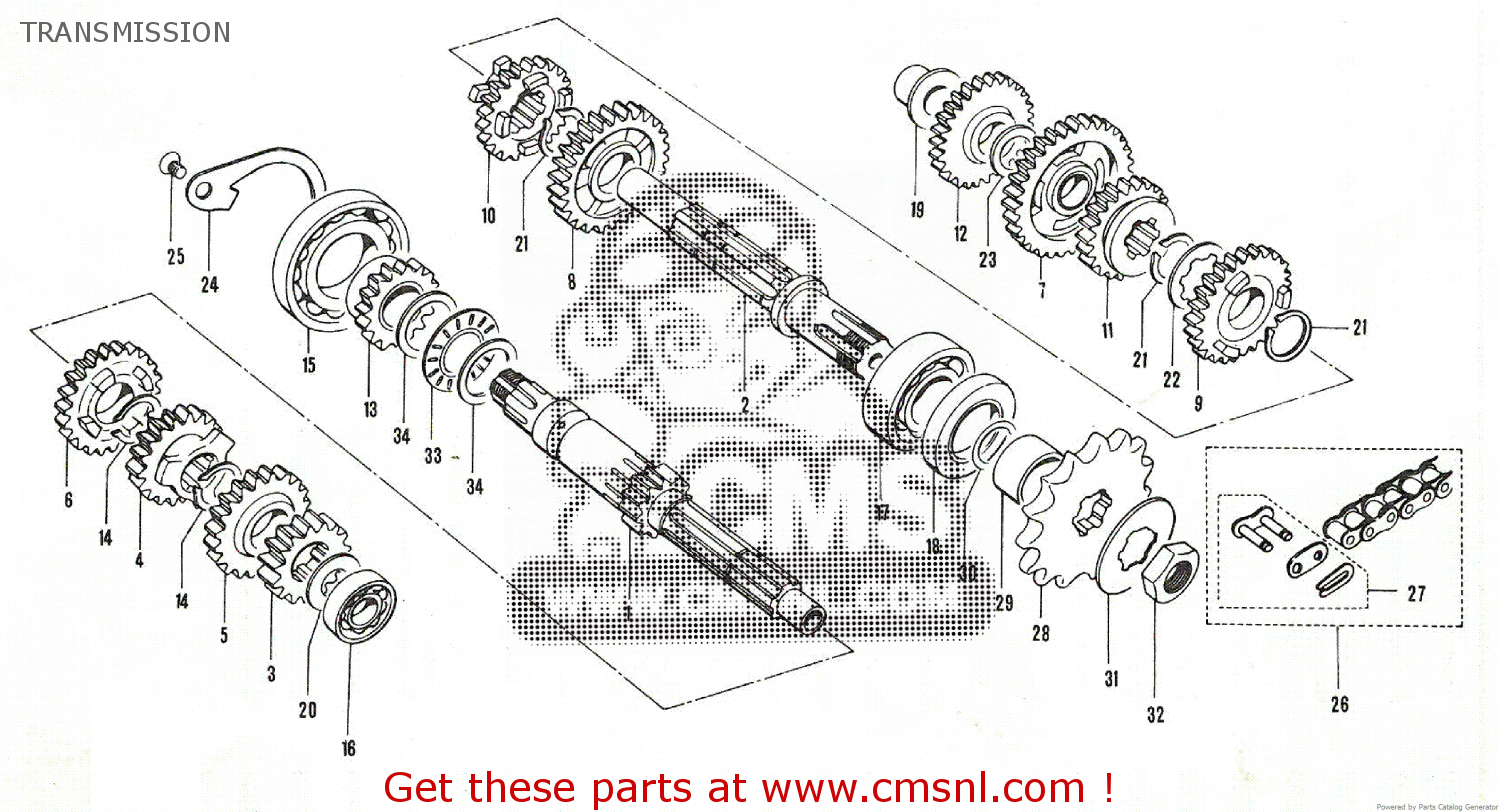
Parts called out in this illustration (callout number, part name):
12	GEAR,KICK STARTER IDLE
13	GEAR,KICK STARTER DRIVEN(NT:16
15	BEARING
16	BALL BEARING
17	Bearing
19	BUSHING
24	PLATE,COUNTERSHAFT BEARING
25	SCREW
27	JOINT ASSEMBLY,CHAIN
33	BEARING 21X35X2.8
34	WASHER(21X30X0.8)
